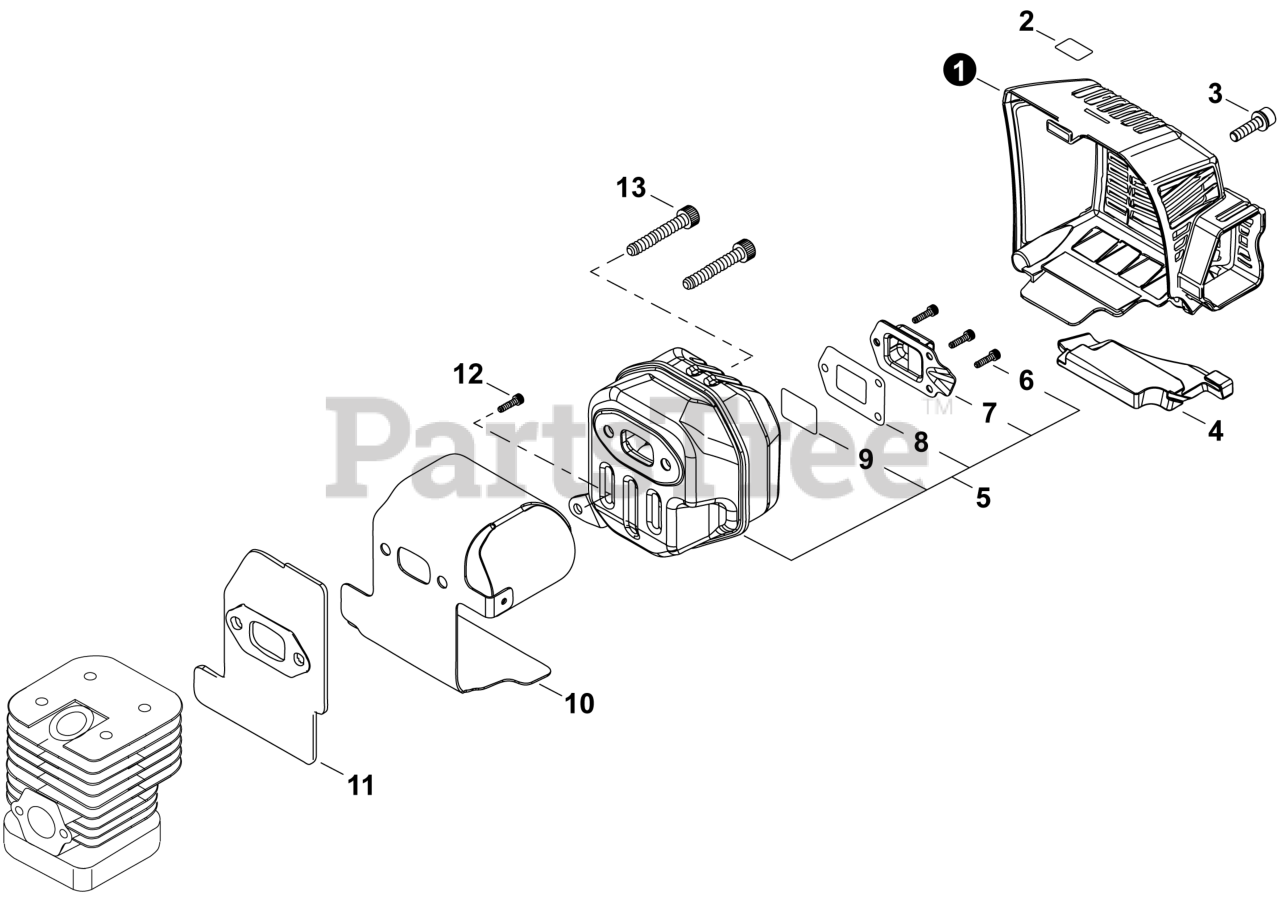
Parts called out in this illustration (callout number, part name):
1	COVER, MUFFLER
2	LABEL - CAUTION - HOT
3	BOLT, TORX 5×25
5	MUFFLER ASSY
6	BOLT, TORX 4×8
7	GUIDE, EXHAUST
8	GASKET, EXHAUST
9	SCREEN, SPARK ARRESTER
10	HEAT SHIELD, EXHAUST
11	GASKET, EXHAUST
12	BOLT, TORX 5×16
13	BOLT, TORX 6×20
